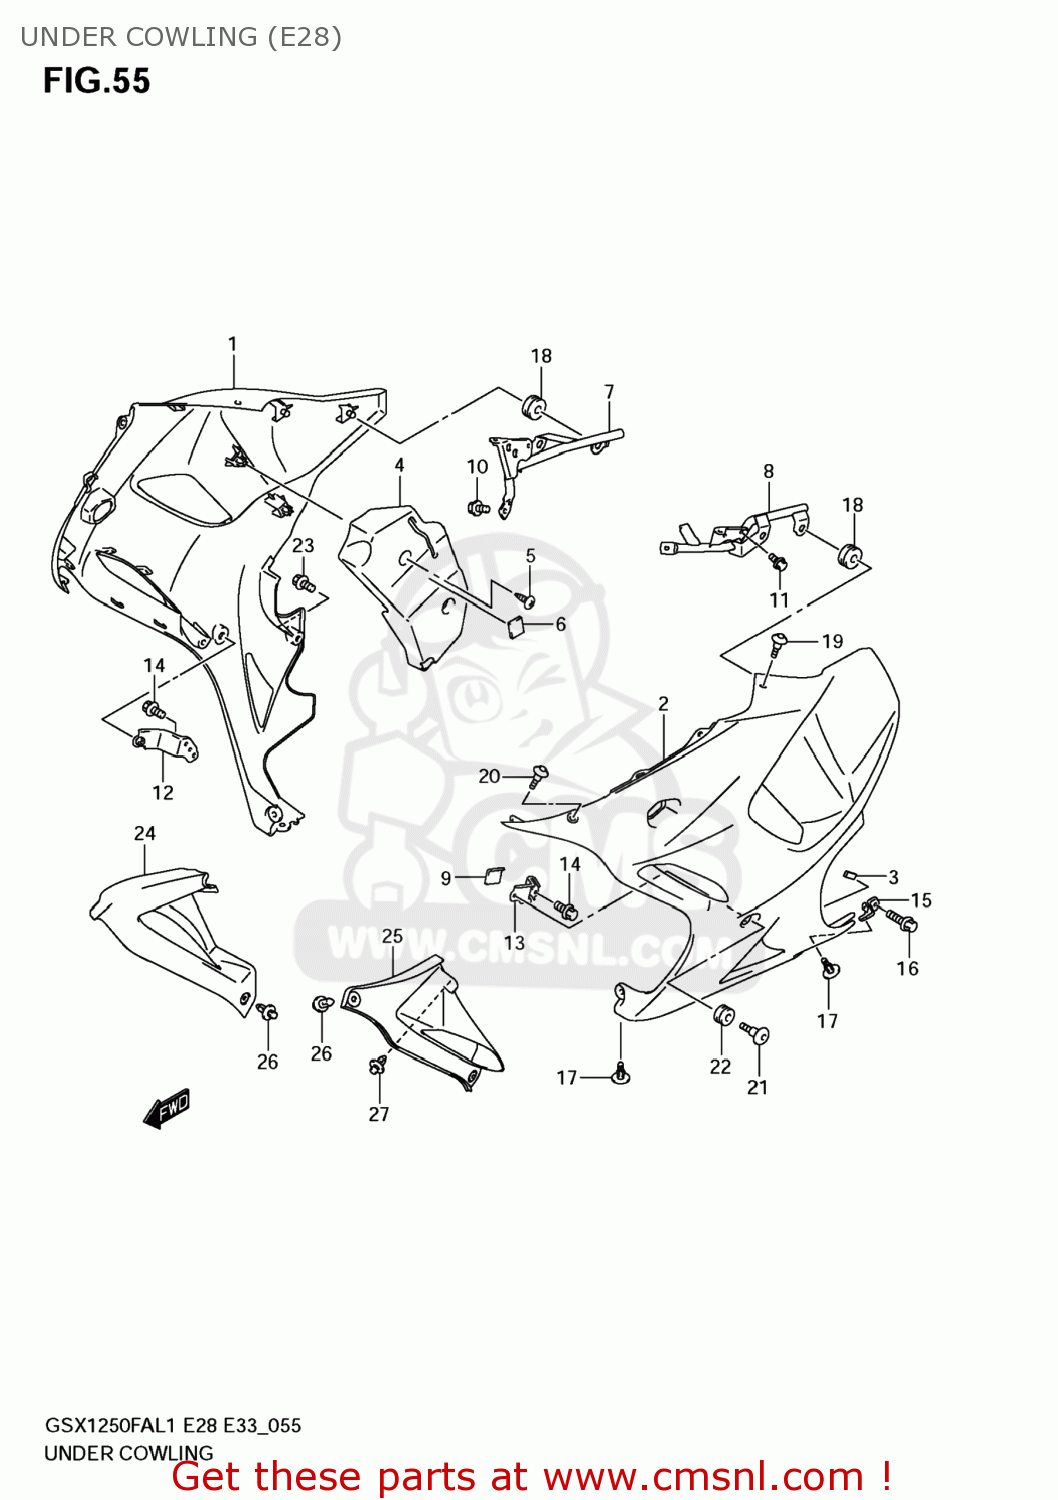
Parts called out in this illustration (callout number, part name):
1	COWLING,UNDER,R
2	COWLING,UNDER,L
3	CUSHION,LICENSE PLATE
4	PROTECTOR,COWLING UNDER,R
5	SCREW
6	CUSHION,UNDER COWL ENG,R NO.1
7	BRACKET,COWLING FITTING,R
8	BRACKET,COWLING FITTING,L
9	PROTECTOR,COWLING UNDER
10	BOLT
11	BOLT
12	BRACKET,UNDER COWLING FR,R
13	BRACKET,UNDER COWLING FR,L
14	BOLT
15	BRACKET,UNDER COWLING LWR,L
16	BOLT(6X25)
17	CLIP
18	CUSHION
19	SCREW(5X16)
20	SCREW(5X13)
21	SCREW(6X20)
22	CUSHION
23	SCREW(6X12)
24	COWLING,UNDER INNER,R
25	COWLING,UNDER INNER,L
26	CLIP
27	CLIP
